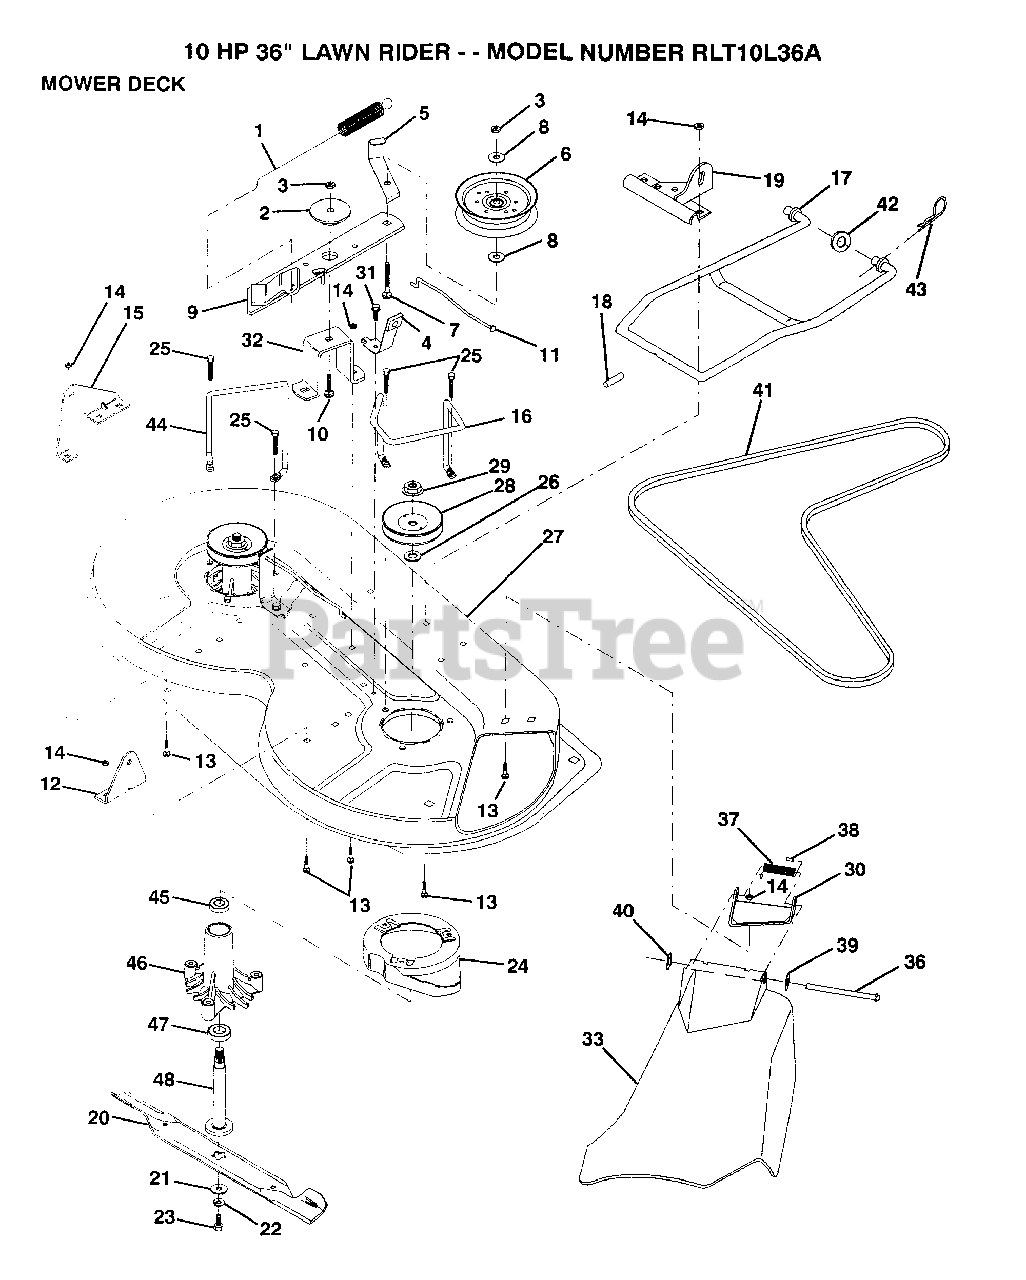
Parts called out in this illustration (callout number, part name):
2	SPACER RETAINER
4	BRAKE ASM
5	IDLER BELT GUIDE
6	PULLEY IDLER
7	BOLT
8	WASHER
10	BOLT D
11	BRAKE ROD
12	"BRKT,LIFT REAR"
13	BOLT
15	"BRKT,LIFT REAR LH"
17	MOWER LINK STAB
18	"PIN,GROOVE"
19	"BRKT,LINK STABILI"
21	WASHER BLADE
23	BLADE BOLT
26	WASHER
31	SCREW LT
32	"SUPT,IDLER ARM"
36	HINGE ROD
37	SPRING TORSION
38	CAP-SLEEVE LT
39	WASHER
40	NUT PUSH M
41	V-BELT.PRIM.78.5.
43	RETAINER.SPRING
45	BEARING
46	HSG ASM MANDREL
47	BEARING.BALL
